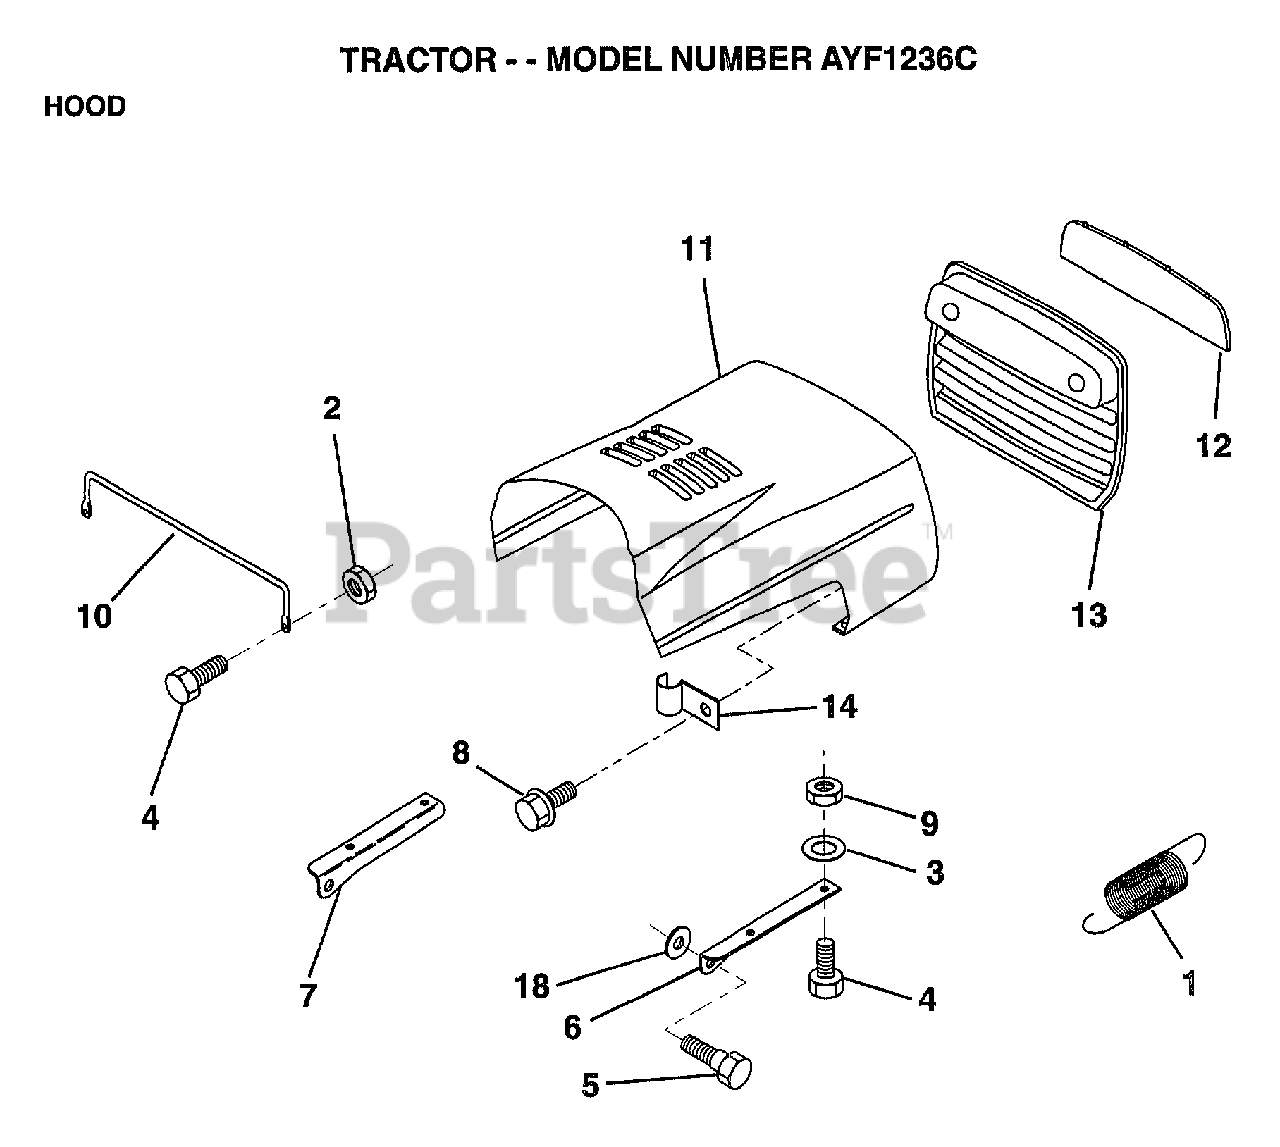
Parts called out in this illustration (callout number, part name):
1	EXT SPRING
2	NUT
3	WASHER
5	BOLT.SHLD.5/16-18
6	BRKT HOOD RH
7	BRKT HOOD LH
8	"SCREW,HWHD.HI-LO#13-16X3/4"
9	NUT
10	"BRACE,HOOD"
11	HOOD.IMPREG.MS550
12	LENS
13	GRILL
18	WASHER
